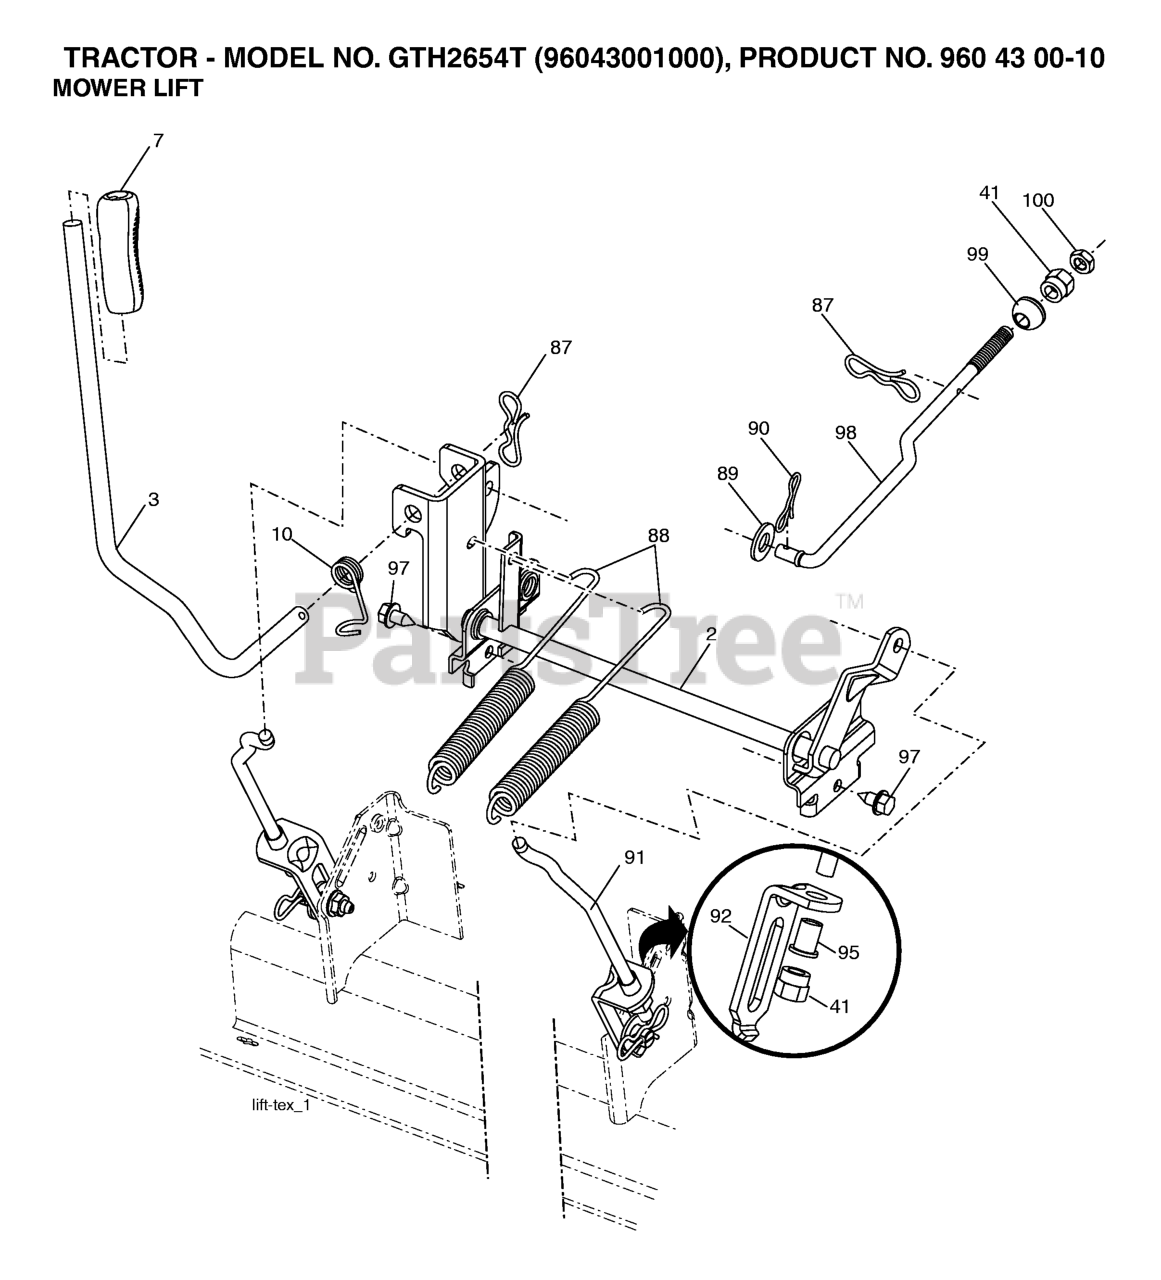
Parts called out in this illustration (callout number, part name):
2	SHAFT.ASM.LIFT.CROSS.H
3	LEVER.LIFT.HANDLE.GT
7	GRIP.LEVER.5625.ID
10	SPRING.TORSION.LIFT.HANDLE
41	NUT, LIFT LINK 7/16-20
87	PIN.COTTER.7/16.BOW TI.
88	SPRING.LIFT.ASSIST.GT2
89	WASHER.CLEAR.ZINC
90	PIN.COTTER.5/16.BOW TI
91	LIFT LINK SUSP. MOWER REAR
97	SCREW 3/8-16X3/4
100	NUT **
